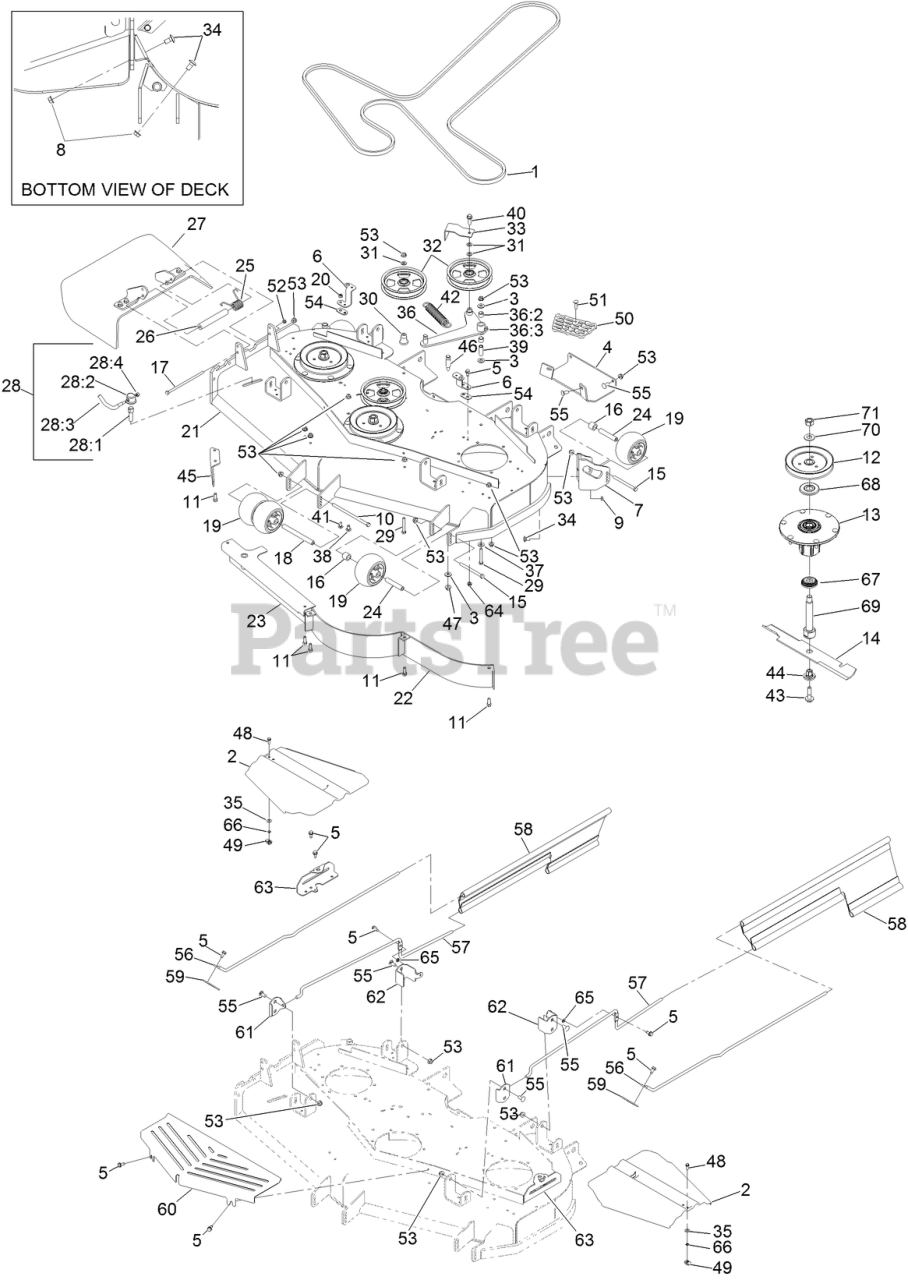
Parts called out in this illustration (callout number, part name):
1	BELT-V
2	COVER-BELT
3	WASHER-FLAT
4	PLATE-SKID
5	SCREW-HWHTF
6	BRACKET-COVER, TALL
7	MOUNT-WHEEL, LH
8	NUT-HHF, WHIZ
10	SCREW-HH
12	PULLEY-B SECTION
13	SPINDLE ASM
14	BLADE-FLOW, HIGH
15	SCREW-HH
16	TUBE-SPACER
17	SCREW-HH
18	SPACER-WHEEL
19	ROLLER-SCALP, ANTI
20	NUT-LOCK, NI
21	DECK ASM
24	TUBE-SPANNER
25	SPRING-TORSION
26	SPACER
27	RUBBER DEFLECTOR ASM
28	LEVER ASM
28:1	SCREW-LOCK
28:2	CAP-LOCK
28:4	NUT-LOCK, NI
29	SCREW-HH
30	MOUNT-PULLEY
31	WASHER-FLAT
32	PULLEY-IDLER, FLAT
33	GUIDE-BELT
34	SCREW-CARR
35	WASHER-THRUST
36	DECK IDLER ARM ASM
36:2	SLEEVE-BEARING
36:3	FITTING-GREASE, 90 DEG
37	WASHER-BELLEVILLE
38	SCREW-CARR
39	BUSHING
40	SCREW-HHF
41	SCREW-CARR
42	SPRING-EXTENSION
43	SCREW-SEMS
44	BUSHING-HEX
45	BAFFLE-DISCHARGE
46	PIN-THREADED, SPRING ANCHOR
47	NUT-HF
48	SCREW-HWH
50	STEP-DECK
51	SCREW-CARR
52	NUT-LOCK, NI
53	NUT-HF, NI
54	SPACER-BELT COVER
55	SCREW-CARR
56	ROD-SUPPORT, UPPER
57	ROD-SUPPORT, LOWER
58	GUARD-SIDE
59	BRACKET-MOUNTING, UPPER ROD
60	SHIELD-FRONT
61	BRACKET-MOUNTING, FRONT
62	BRACKET-MOUNTING, REAR
63	BRACKET-SUPPORT, SPINDLE COVER
64	NUT-HF, NI
65	NUT-PUSH
66	PUSHNUT-RETAINER, BOLT
67	GUARD-BOTTOM
68	GUARD-BEARING, TOP
69	SHAFT-SPINDLE
70	WASHER
71	NUT-HEX
